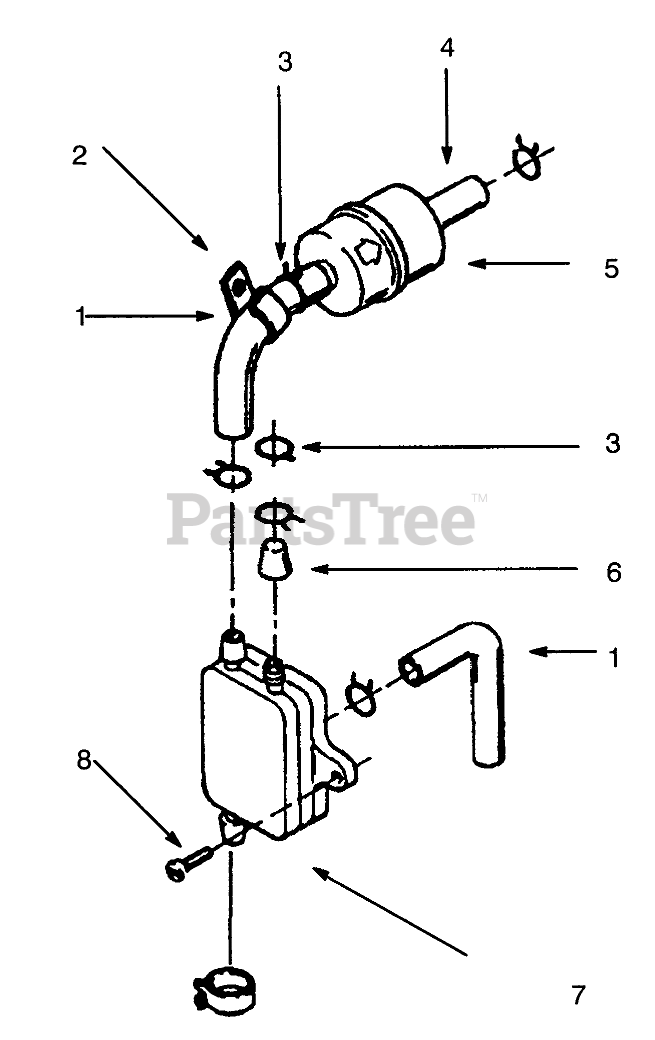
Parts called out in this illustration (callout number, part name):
1	Hose
2	Clip
3	CLAMP-HOSE
4	FUEL HOSE
5	Filter-Fuel
6	CAP-FUEL OUTLET
7	PUMP-FUEL
8	SCREW-TAPPING PAN HD
